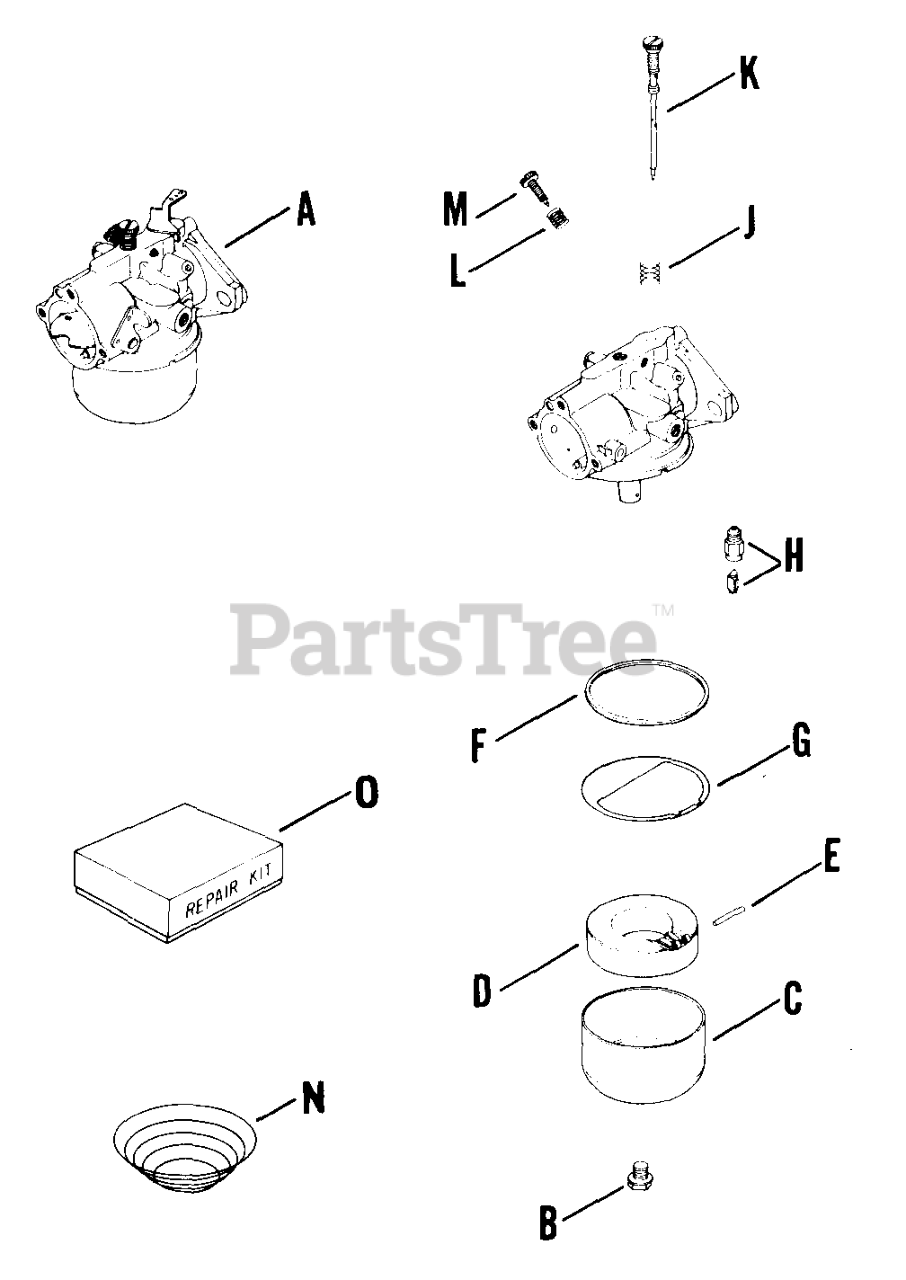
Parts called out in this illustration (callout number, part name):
A	CARBURETOR - DISCONTINUED
B	NUT - DISCONTINUED
D	KIT - USE 25 757 03
G	GASKET - USE 25 041 01
H	NEEDLE - USE 231555
K	NEEDLE - Discontinued
L	SPRING-(#DSC)
M	SCREW - DISCONTINUED
O	KIT - USE 25 757 01
